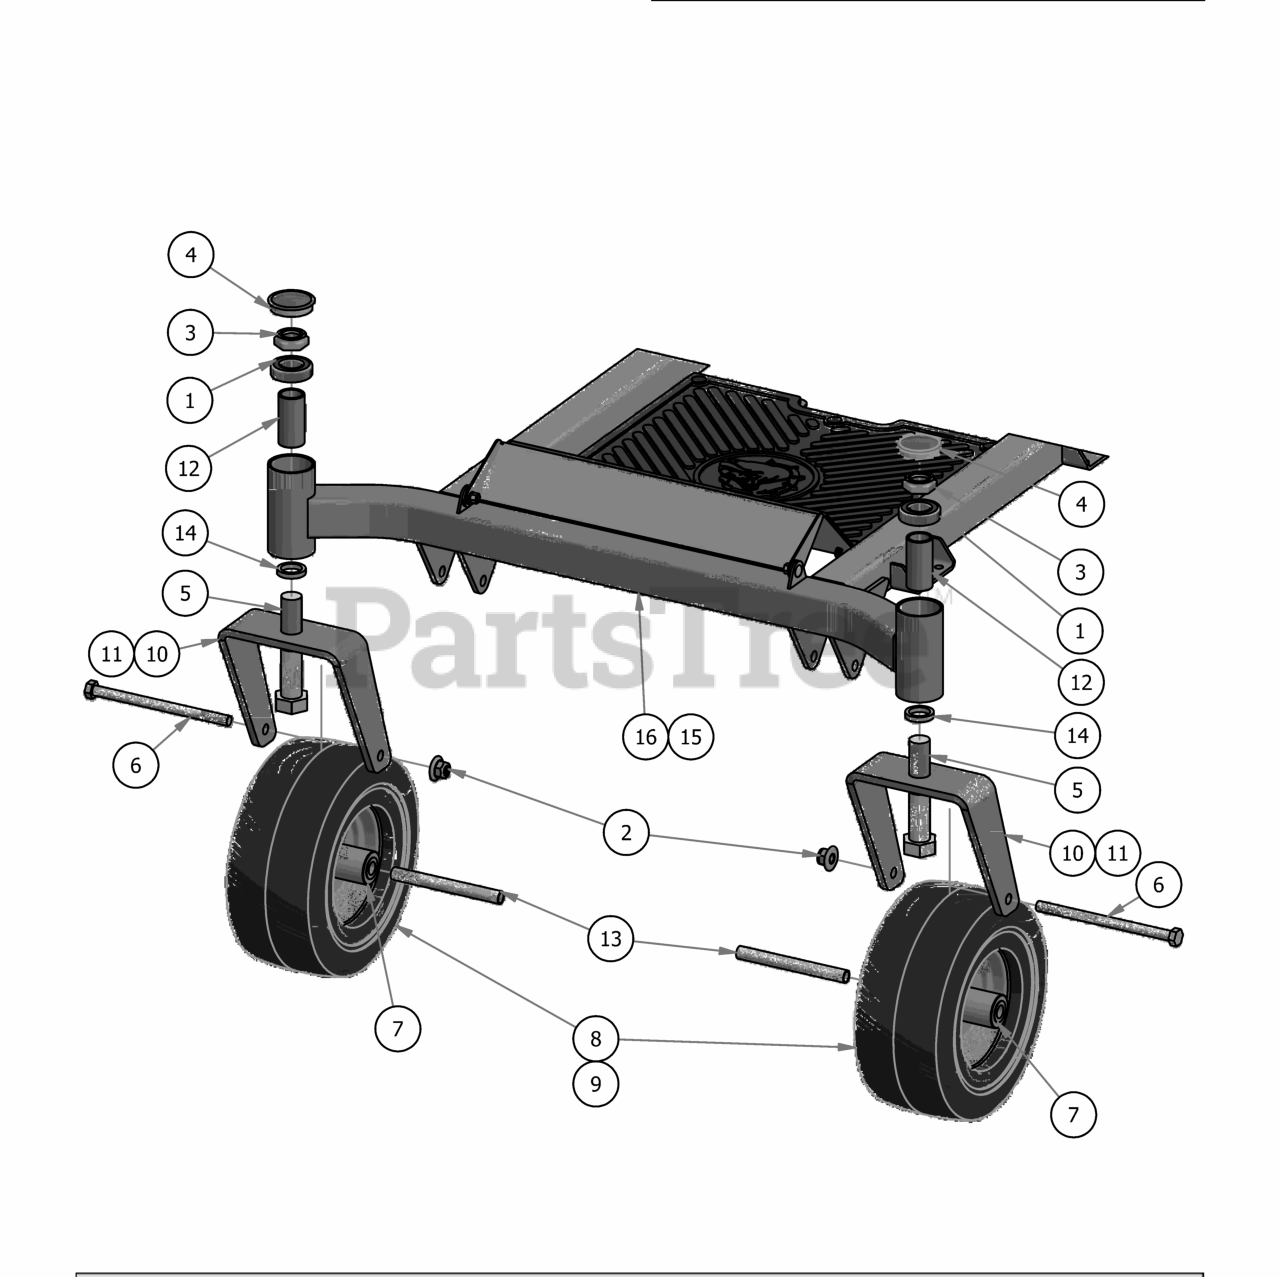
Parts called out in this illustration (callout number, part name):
1	Caster Bearing 2016 - 1641 Bearing
2	1/2-13 Nylon Flange Nut
3	1" Fine Thread 1/2 Nylock Nut
4	2017 Bearing Cover
5	1-14 x 5 Hex Bolt Grade 8 Zinc Yellow
6	1/2 -13 x 7.5 Hex Bolt Grade 5
7	Front Wheel Bearing
8	11x6-5 front tire & wheel assembly
9	11x4-5 MZ Front Tire Assembly (42" MZ Only)
10	2017 MZ Front fork
11	MZ 8mm Front Fork (42" MZ Only)
12	2016 Front Bearing Spacer
13	Front Wheel Spanner
14	Spacer, 1x1.375x.25
15	2017 MZ/ZT 54"-60" Frame
16	2017 MZ/ZT 42"-48" Frame
